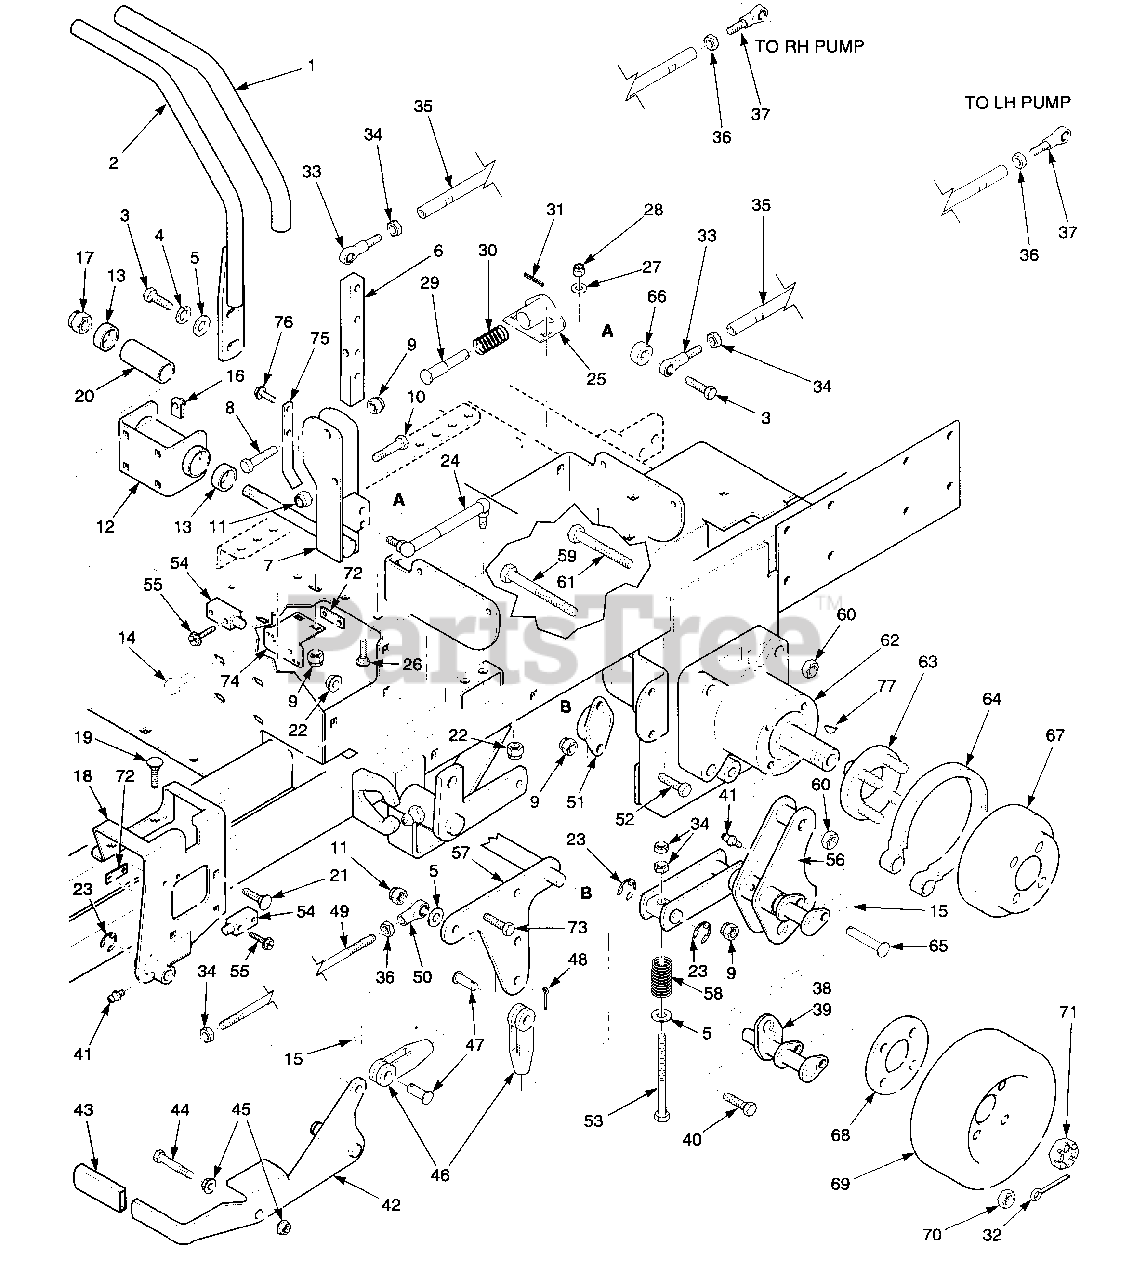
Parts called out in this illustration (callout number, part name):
1	Grip, Handle Bar
2	Handle Bar
3	Bolt, Hex Head 3/8-16 x 1-1/4"
4	Lockwasher, 3/8"
5	Flatwasher. 3/8" (.391 x .938 x .105)
6	Bar, Control Lever
7	Control Lever
8	Bolt, Hex Head 5/16-18 x 2"
9	Nut, Hex Elastic Stop 5/16-18
10	Bolt, Hex Head 3/8-16 x 2"
11	Nut, Hex Elastic Stop
12	Bracket, Control
13	Ball Bearings, Neutral Return
14	Bolt, Hex Head 5/16-18 x 1-1/4"
15	Pin, Rue Cotter 3/8 DIA
16	U-Nut, 5/16-18
17	Nut, Hex Elastic Stop 5/8-11
18	Bracket, Control Lever LH
19	Bolt, Carriage 5/16-18 x 1"
20	Spacer, Bearing
21	Bolt, Carriage 5/16-18 x 3/4"
22	Nut, Hex Serrated Flange 5/16-18
23	Ring, Retaining 5/8" External "E"
24	Gas Damper
25	Bracket, Neutral Return
26	Bolt, Carriage 1/4-20 x 3/4"
27	Flatwasher, 1/4" (.312 x .750 x .065)
28	Nut, Hex Elastic Stop 1/4-20
29	Pin, Retaining Spring
30	Spring
31	Roll Pin, Spring 5/32 x 3/4"
32	Pin, Cotter 9/16 x 1-1/2"
33	Rod End, Male 3/8-24 RH THD.
34	Nut, 3/8-24 RH THD.
35	Tube, Control Link
36	Nut, Hex 3/8-24 LH THD.
37	Rod End, Male 3/8-24 LH Tl-ID.
38	Brake Linkage Weldment LH
39	Brake Linkage Weldment RH
40	Bolt, Hex Head 5/16-18 x 1"
41	Grease Fitting
42	Lever, Parking Brake
43	Grip, Parking Brake
44	Bolt, Hex Head 3/8-16 x 2-3/4"
45	Nut, Hex Serrated Flange 3/8-16
46	Clevis, Traction Control
47	Pin, Clevis 3/8-16 x 1-1/16"
48	Pin, Cotter 3/32 x .75
49	Rod, Parking Brake
50	Rod End, LH THD.
51	Bushing, Self Align
52	Bolt, Hex Head 5/16-18 x 3/4"
53	Bolt, Hex Head 3/8-24 x 5-1/4", 2-3/4" Thread
54	Switch
55	Screw, Hex SLTD WSHR Head #10-32 x 3/4"
56	Brake Linkage, LH
57	Bellcrank, Brake Actuator
58	Spring
59	Bolt, Hex Head 1/2-13 x 3-1/2"
60	Locknut, Hex 1/2-13 Center Lock
61	Bolt, Hex Head 1/2-13 x 2-1/2"
62	Wheel Motor, Ross
63	Wheel Hub Assembly
64	Brake Band Assembly
65	Pin, Clevis 3/8" Dia. x 2"
66	Spacer
67	Brake Drum
68	Spacer, Wheel
69	Wheel Assembly 24 x 12-12 Turf Master
70	Lug Nut, 1/2-20
71	Nut, Hex Castle
72	Plate, Threaded
73	Bolt, Hex Head 3/8-16 x 1-1/2"
74	Bracket, Switch Mounting
75	Bracket, Switch Actuator
76	Bolt, Hex Serrated Flange 5/16-18 x 3/4"
77	Key, Woodruff 5/16 x 1"
